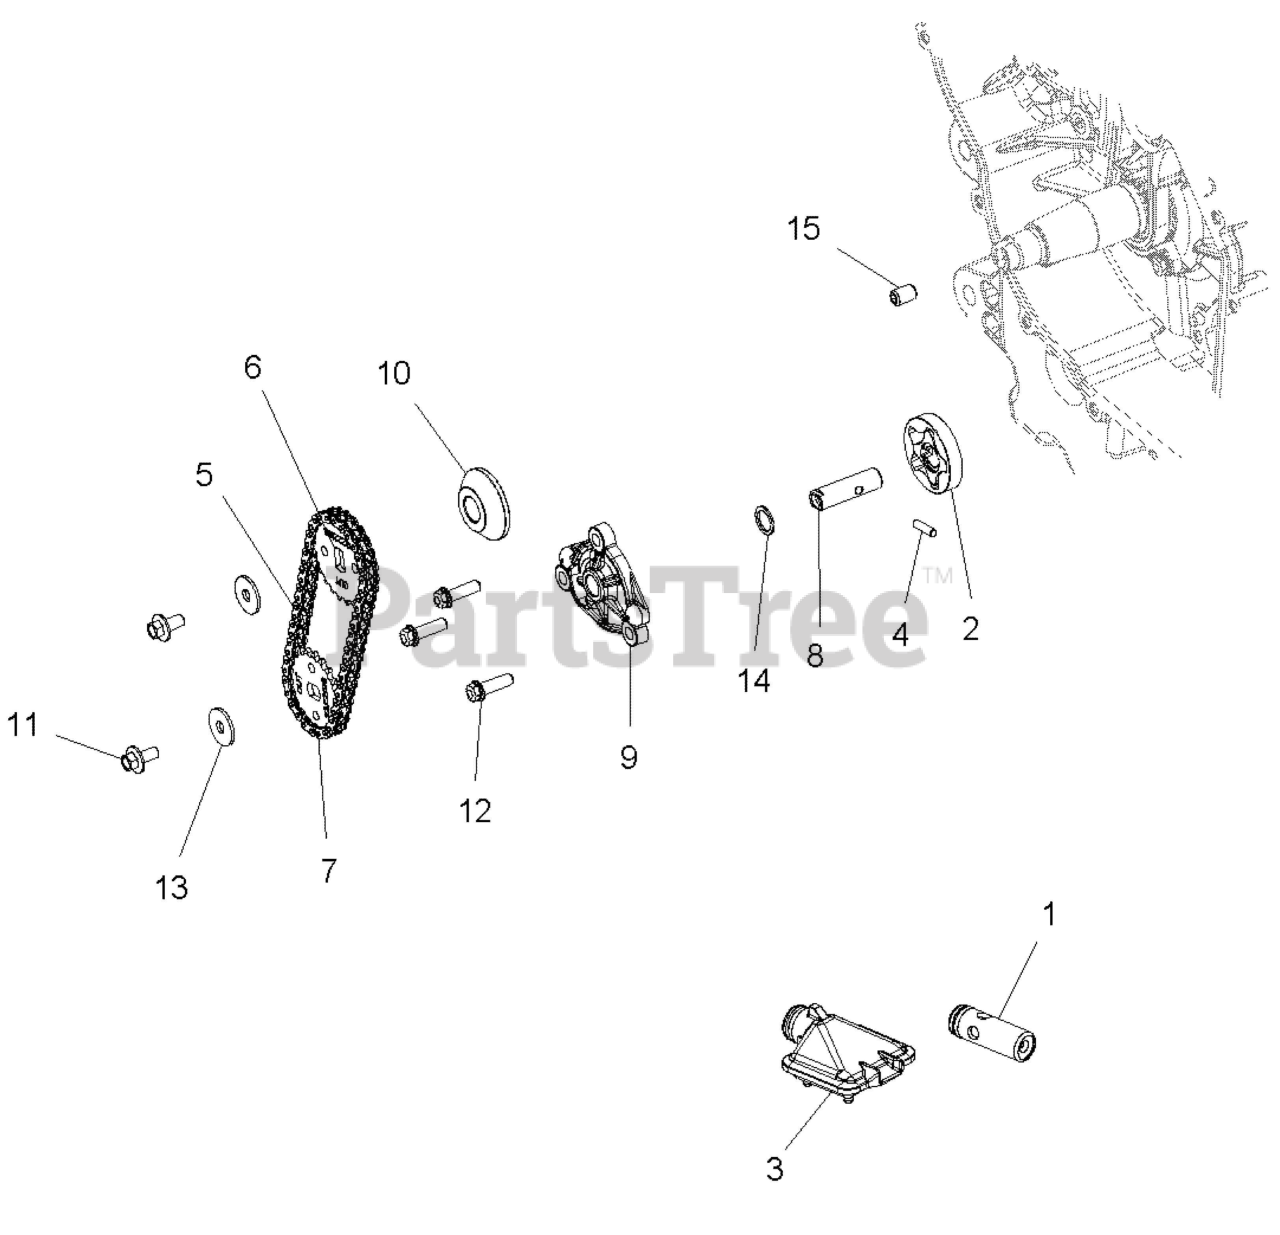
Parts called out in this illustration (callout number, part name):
1	ASM, REGULATOR VALVE
2	ASM-GEROTOR
3	ASM-OIL PICKUP
4	PIN-SOLID,M4X15.8
5	CHAIN-OIL PUMP DRIVE
6	SPROCKET-23T,DRIVE
7	SPROCKET-21T,DRIVEN
8	SHAFT-OIL PUMP
9	COVER-OIL PUMP,MACH
10	SPACER-SPROCKET
11	SCREW,HXFLGHD,M6X12
12	SCR-M6X20,HXFLG,0600214
14	WASHER-11.2X15.0X1.0
15	JET-OIL,OIL PUMP
